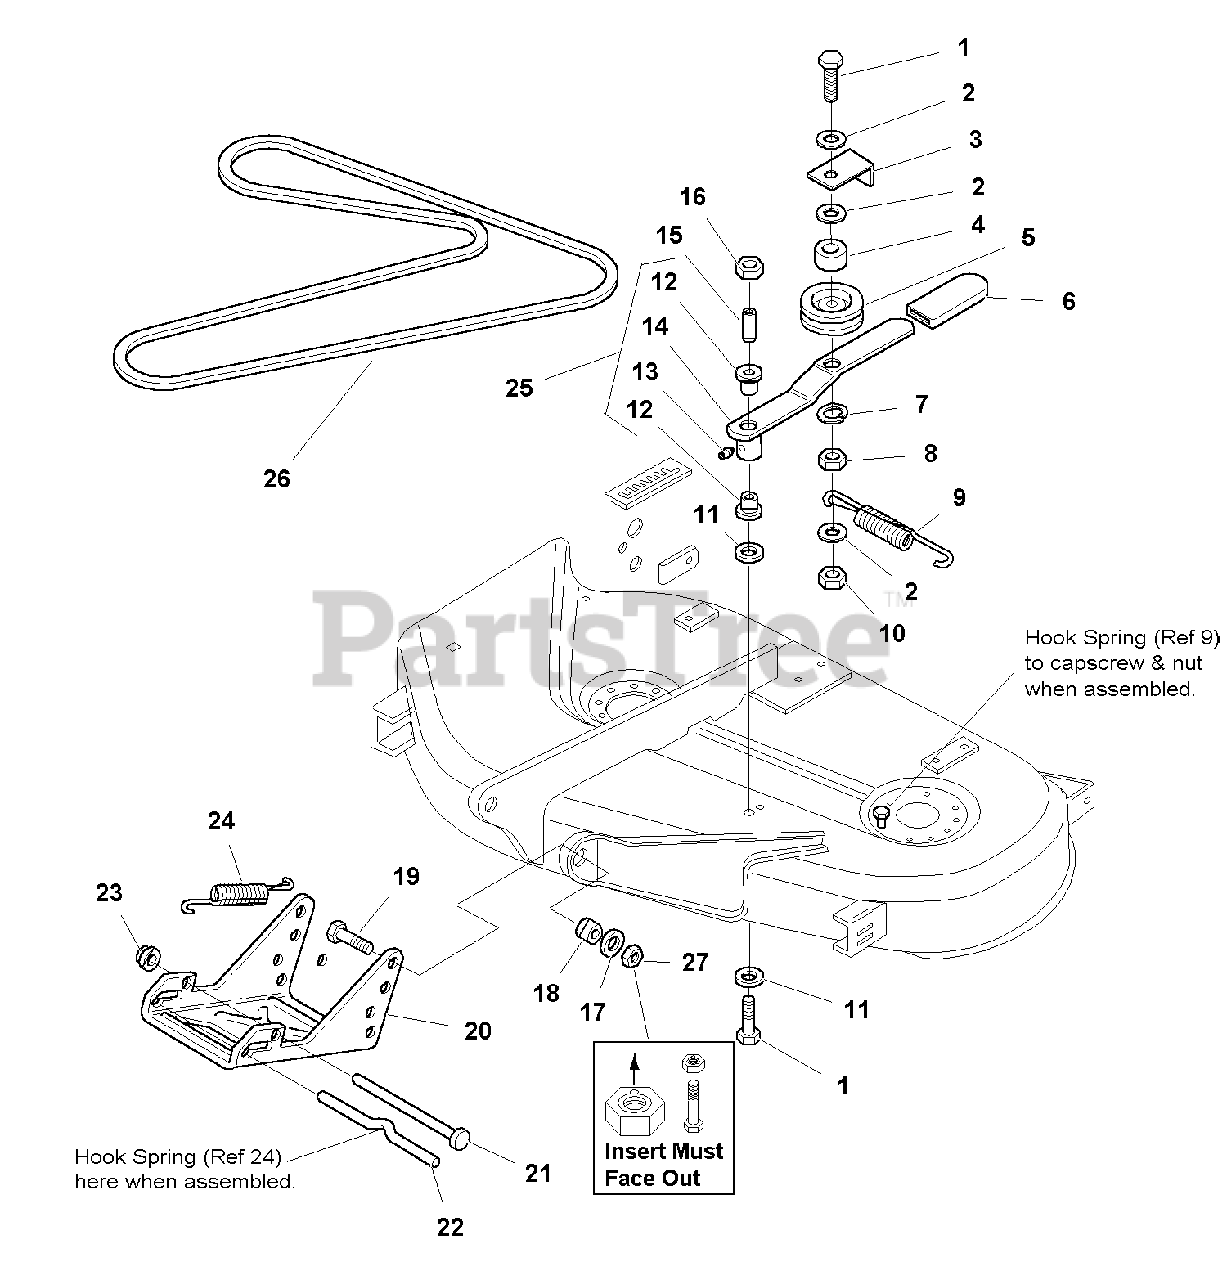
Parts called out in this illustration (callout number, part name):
1	CAPSCREW, Hex Head, 3/8-16 x 2-3/4 G8
2	WASHER, Plain, 3/8
3	GUARD, Spring
5	PULLEY ASSEMBLY KIT, (Includes Ref. No. 4)
6	GRIP, Lever
7	LOCKWASHER, 3/8
8	NUT, Hex, 3/8-16
9	SPRING, Idler Arm
10	NUT, ESNA Hex Lock, 3/8-16
11	WASHER , 3/8
12	BUSHING, 5/8, Nylon
13	FITTING, Grease
16	NUT, Hex Flange Lock, 3/8-16
17	WASHER, Plain, 3/8
19	CAPSCREW, Hex Head, 3/8-16 x 1-3/8
21	ROD, Mower Hitch
23	NUT, Push, 1/2
24	SPRING, Hitch Release
25	CLUTCH LEVER ASSEMBLY w/ BUSHINGS, (Includes Ref. Nos. 12, 13, and 14)
26	V-BELT, Arbor Drive
27	NUT, Hex Lock Aluminum Insert, 3/8-16
